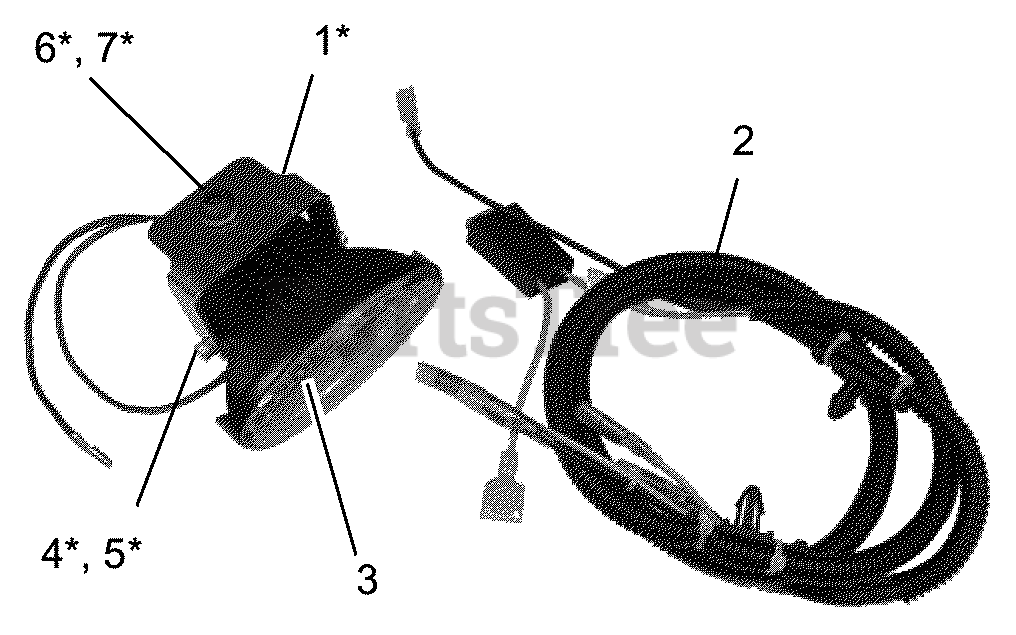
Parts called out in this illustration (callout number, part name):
1	Light Bracket Weldment
2	Mini-Z Headlight Harness
3	Light, Consumer Ride-On
4	4 mm x 1 mm Regular Cone Lock Washer
5	4 mm x .07 mm x 8 mm Socket Head Cap Screw
6	5/16" x 5/64" Lock Washer
7	5/16"-18 x 1/2" Grade 5 Button Head Cap Screw
